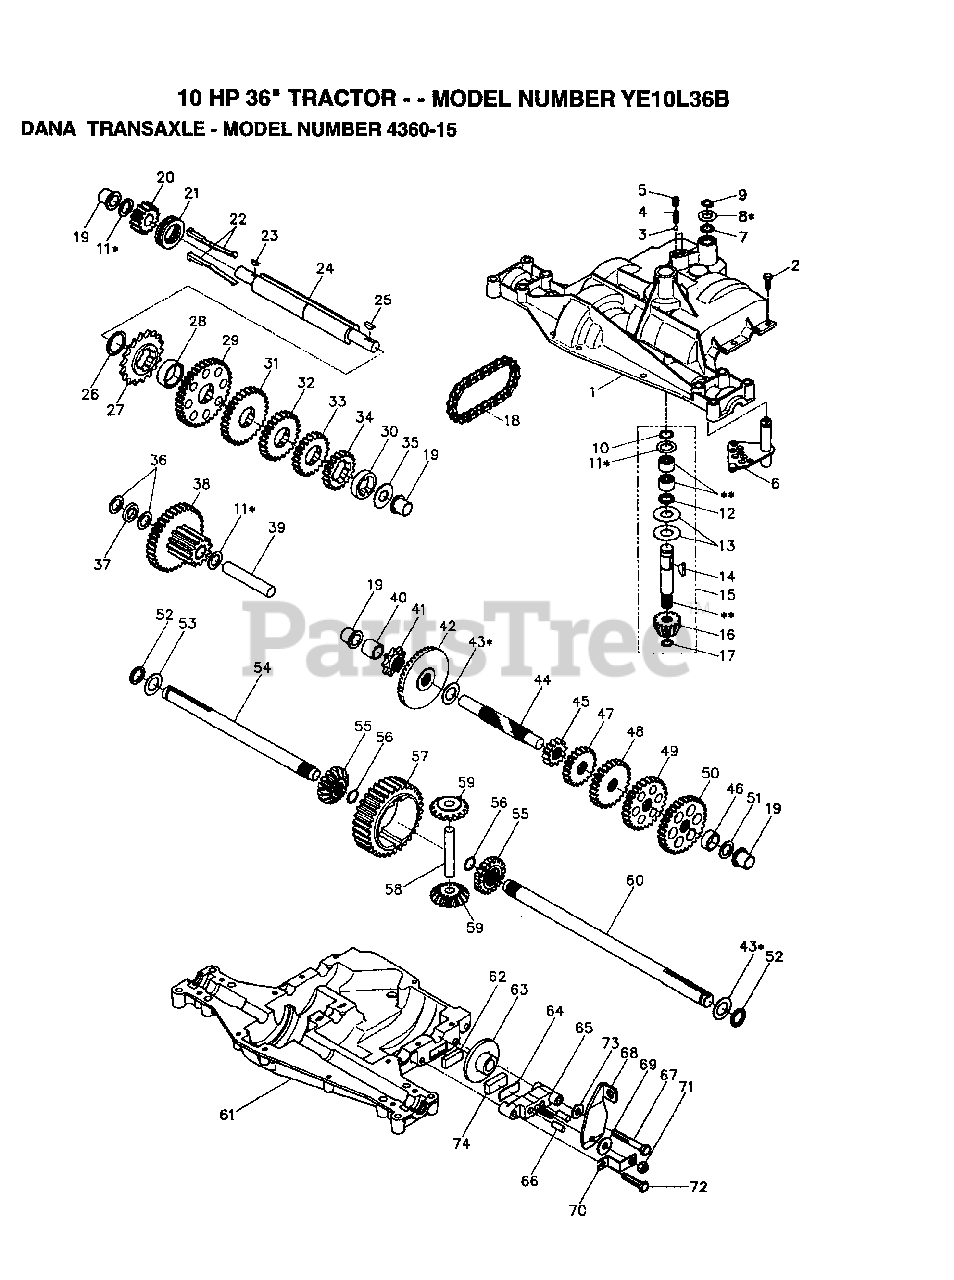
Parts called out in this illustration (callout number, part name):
1	HOUSING UPPER
3	BALL DETENT
4	SPRING, DETENT
5	SCREW, SET
6	ASSY SHIFTER
8	WASHER PLAIN
9	RING RETAINING
10	RING RETAINING
11	WASHER PLAIN
13	WASHER, PLAIN .632 X 1.38 X .046
14	KEY WOODRUFF #9
15	ASSY KIT INPUT SHAFT
16	PINION, BEVEL, 14 TEETH
17	RING, RETAINING
18	CHAIN, 24 PITCHES
19	BEARING, FLANGE
20	GEAR SPUR, 14 TEETH
21	COLLAR CLUTCH
22	KEY CLUTCH
23	KEY WOODRUFF #3
24	SHAFT INTERMEDIATE
25	KEY, WOODRUFF, #61
26	RING, RETAINING
27	SPROCKET, 18 TEETH
29	GEAR, SPUR, 37 TEETH
31	GEAR, SPUR, 30 TEETH
32	GEAR, SPUR, 25 TEETH
33	PUCK, FRICTION
35	WASHER, PLAIN .640 X 1.37 X .061
36	WASHER, PLAIN .632 X 1.00 X .026
37	SPACER .630 X 1.00 X .169
38	ASSY GEAR COMB 12&35 TEETH
39	SHAFT IDLER
40	SPACER .635 X .875 X .755
41	SPROCKET, 9 TEETH
42	GEAR, BEVEL, 42 TEETH
43	WASHER PLAIN
44	SHAFT, DRIVE
45	GEAR, SPUR, 12 TEETH
46	SPACER .781 X 1.00 X .750
47	GEAR, SPUR, 20 TEETH
48	GEAR, SPUR, 25 TEETH
49	WASHER PLAIN
50	GEAR, SPUR, 31 TEETH
51	WASHER, PLAIN .632 X 1.00 X .060
53	WASHER PLAIN
54	AXLE LEFT HAND
55	GEAR, MITER, 15 TEETH
56	RING, RETAINING
57	GEAR, SPUR, 32 TEETH
58	SHAFT, CROSS
59	GEAR, MITER, 15 TEETH
60	AXLE RIGHT HAND
61	HOUSING LOWER
62	PUCK, FRICTION
63	DISC, BRAKE
65	JAW, BRAKE
66	PIN, DOWEL
67	SCREW TAPPING
68	LEVER, ACTUATING
69	WASHER, PLAIN .321 X 1.00 X .055
70	BRACKET, ANTI-ROTATION
71	LOCKNUT 5/16-24
72	SCREW TAPPING
